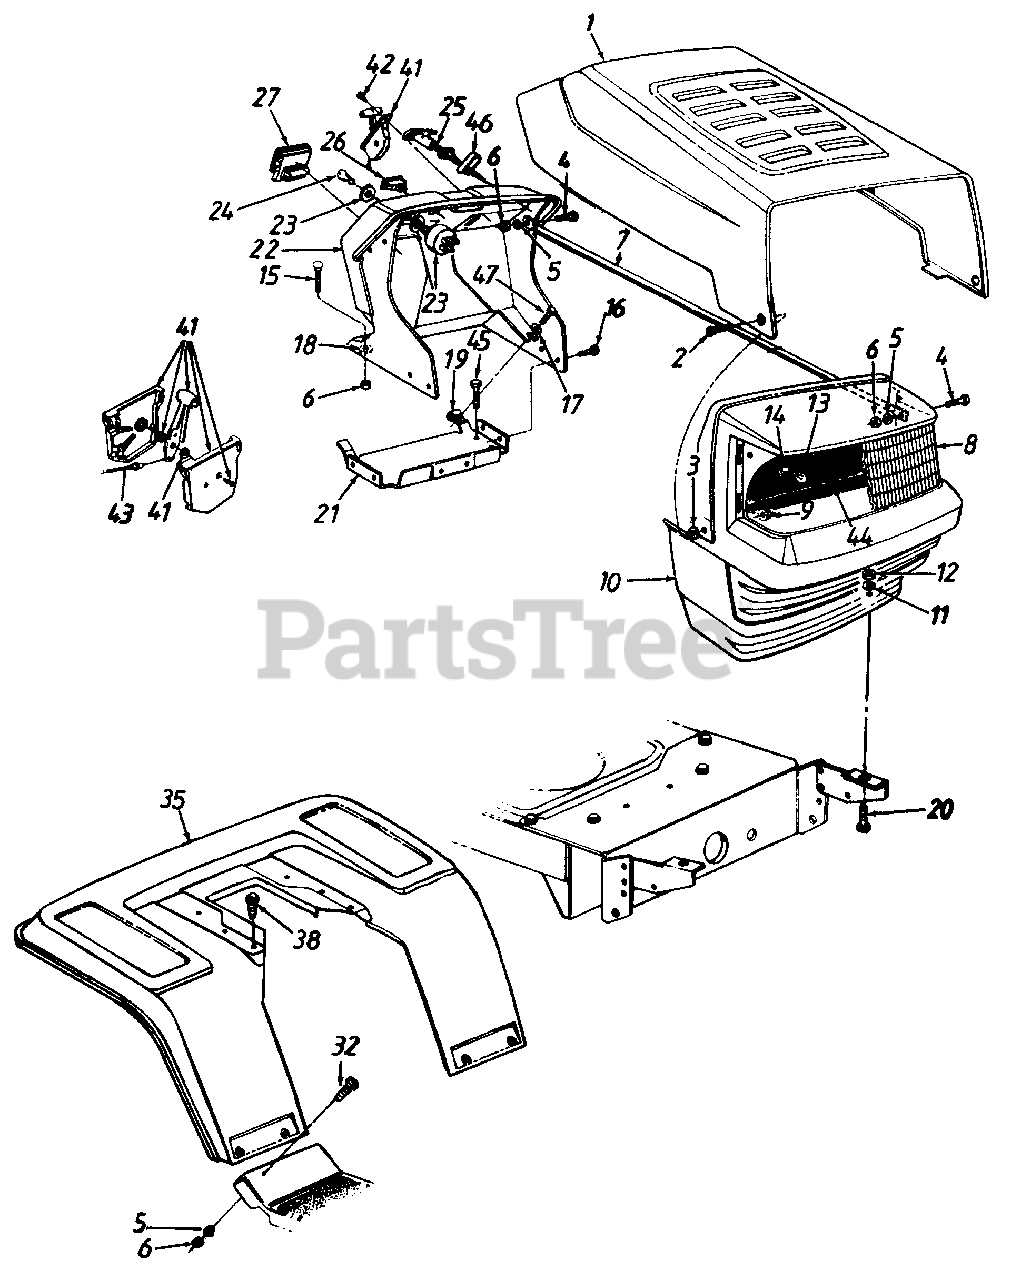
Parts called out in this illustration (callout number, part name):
3	Fl-Wash. .28" I.D. x .75" O.D.
4	Hex Bolt 1/4-20 x .62" Lg.
5	L-Wash. 1/4" I.D.
6	Hex Nut 1/4-20 Thd.
8	Headlight Lens
9	Flange L-Nut 1/4-28 Thd.
10	Grille
11	Fl-Wash. .344" I.D. x 1" O.D.
12	Hex Nut 5/16-18 Thd.
13	Lamp
14	Socket
15	Carriage Bolt 1/4-20 x .75" Lg.
16	Hex Wash. Hd. TT-Tap Scr. 1/4-20 x .5" Lg.
17	Fl-Wash. .281" I.D. x .73" O.D.
18	Bolt Retainer 1/4" I.D.
19	Speed Nut 1/4-20 Thd.
20	Hex Bolt 5/16-18 x .75" Lg.
23	Ignition Switch
24	Ignition Key
25	Choke Control
26	Light Switch
27	Ammeter
32	Truss Mach. Scr. 1/4-20 x .5" Lg.
41	Throttle Box Ass'y.
42	Truss Mach. AB-Tap Scr. #10 x .5" Lg.
43	Throttle Control Wire
44	Grille Reflector Label
45	Hex Wash. Hd. B-Tap Scr. 5/16-18 x .5" Lg.
46	Choke Retainer
47	Hex TT-Tap Scr. 1/4-20 x .75" Lg.
